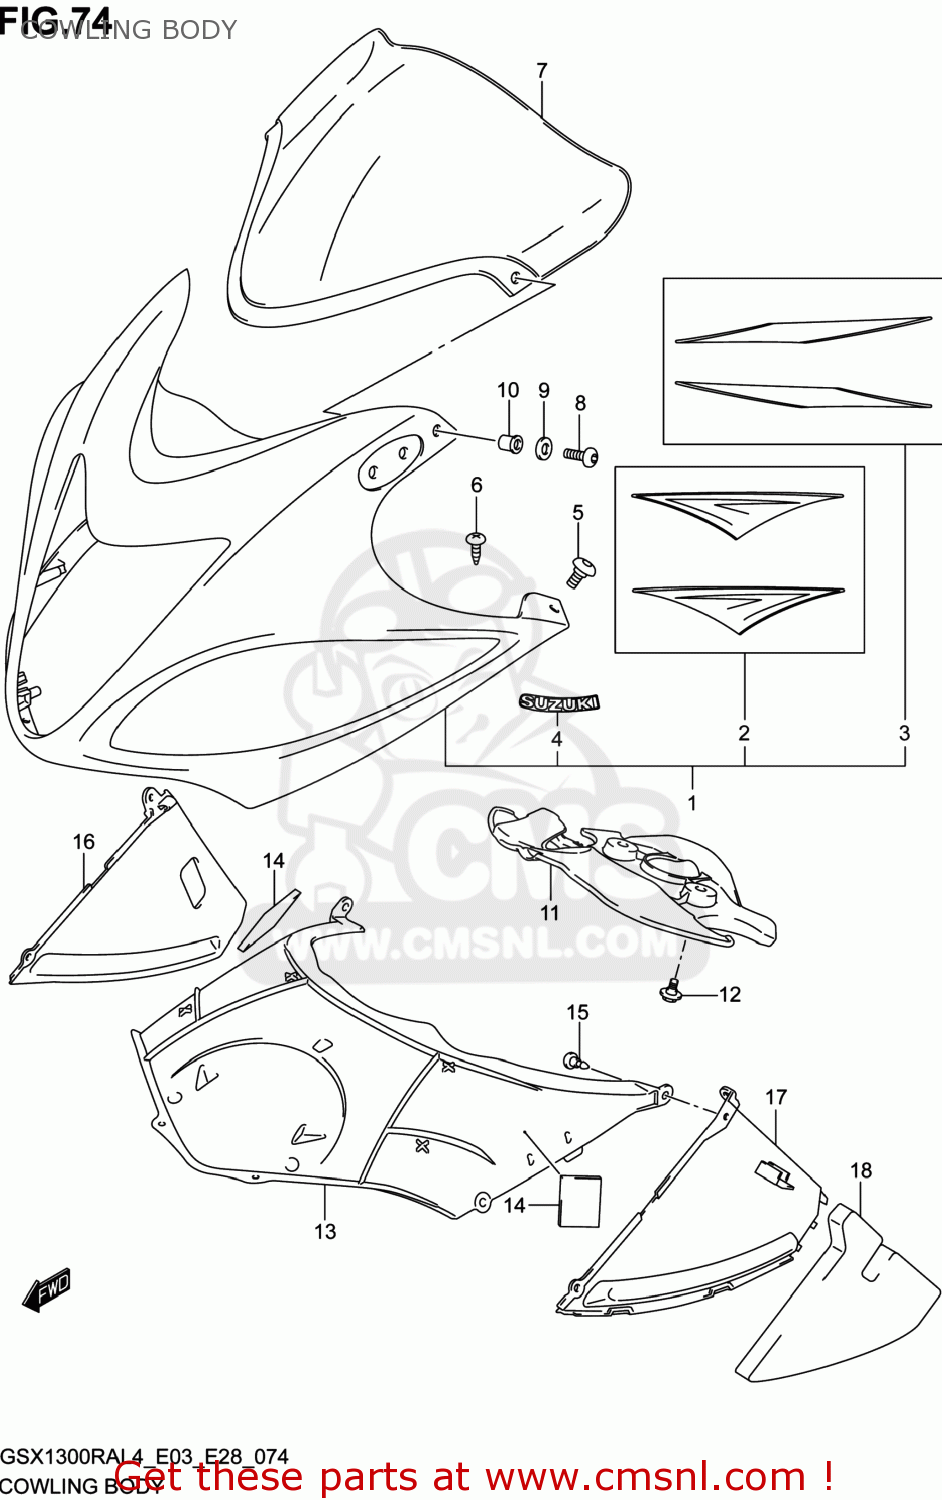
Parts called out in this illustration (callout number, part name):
1	COWLING ASSY,BODY
2	TAPE SET,BODY COWLING UPPER
3	TAPE SET,BODY COWLING LOWER
4	EMBLEM,SUZUKI
5	SCREW(5X16)
6	SCREW(5X16)
7	WINDSCREEN
8	SCREW(5X14)
9	WASHER
10	NUT
11	COVER,LWR BRACKET
12	BOLT(6X12)
13	COVER,BODY COWLING
14	COVER
15	CLIP(BLACK)
16	COWLING,UNDER INNER,R
17	COWLING,UNDER INNER,L
18	CUSHION,INNER COWL,L
